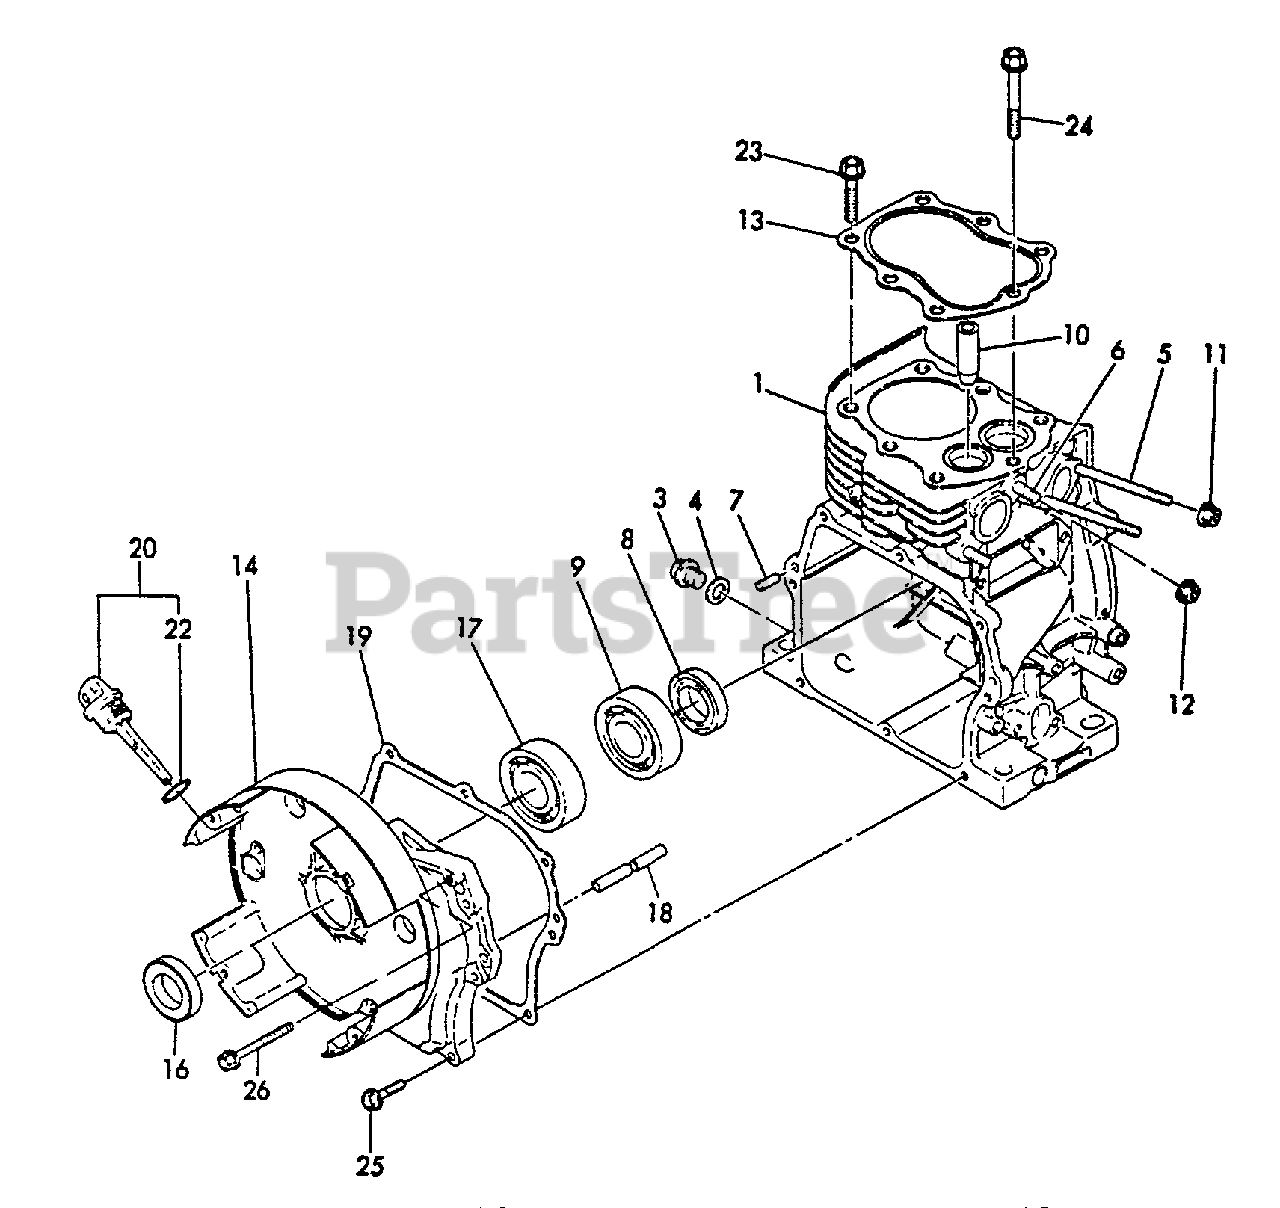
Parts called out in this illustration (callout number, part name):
1	CYLINDER BLOCK SET
3	PLUG, DRAIN
4	GASKET
5	BOLT - 6X70
6	STUD - 8X18 -- PLATED
7	PIN - 6X16
8	SEAL, OIL
9	BEARING, BALL - 6205C3
10	GUIDE, VALVE
11	NUT - 6 -- FLANGE
12	NUT - 8
13	GASKET, CYLINDER
14	SIDE COVER ASSY
16	SEAL, OIL
17	BEARING, BALL - 6205C3
18	SHAFT, GOVERNOR
19	GASKET, SIDE COVER
20	CAP ASSY
22	O-RING - 18
23	BOLT - 8X38
24	BOLT - 8X65
25	BOLT - 6X25
26	BOLT - 6X55
